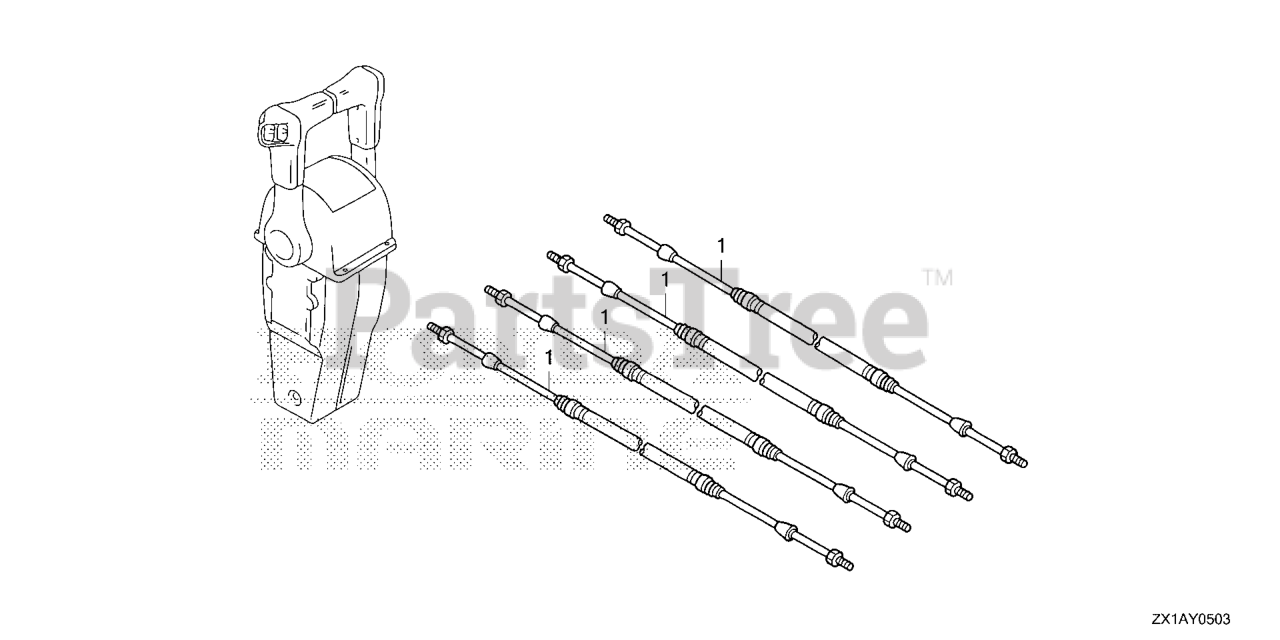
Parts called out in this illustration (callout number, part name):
1	CABLE ASSY., PUSH-PULL (33HPC-5FT)
1	CABLE ASSY., PUSH-PULL (33HPC-6FT)
1	CABLE ASSY., PUSH-PULL (33HPC-7FT)
1	CABLE ASSY., PUSH-PULL (33HPC-8FT)
1	CABLE ASSY., PUSH-PULL (33HPC-9FT)
1	CABLE ASSY., PUSH-PULL (33HPC-10FT)
1	CABLE ASSY., PUSH-PULL (33HPC-11FT)
1	CABLE ASSY., PUSH-PULL (33HPC-12FT)
1	CABLE ASSY., PUSH-PULL (33HPC-13FT)
1	CABLE ASSY., PUSH-PULL (33HPC-14FT)
1	CABLE ASSY., PUSH-PULL (33HPC-15FT)
1	CABLE ASSY., PUSH-PULL (33HPC-16FT)
1	CABLE ASSY., PUSH-PULL (33HPC-17FT)
1	CABLE ASSY., PUSH-PULL (33HPC-18FT)
1	CABLE ASSY., PUSH-PULL (33HPC-19FT)
1	CABLE ASSY., PUSH-PULL (33HPC-20FT)
1	CABLE ASSY., PUSH-PULL (33HPC-21FT)
1	CABLE ASSY., PUSH-PULL (33HPC-22FT)
1	CABLE ASSY., PUSH-PULL (33HPC-23FT)
1	CABLE ASSY., PUSH-PULL (33HPC-24FT)
1	CABLE ASSY., PUSH-PULL (33HPC-25FT)
1	CABLE ASSY., PUSH-PULL (33HPC-26FT)
1	CABLE ASSY., PUSH-PULL (33HPC-27FT)
1	CABLE ASSY., PUSH-PULL (33HPC-28FT)
1	CABLE ASSY., PUSH-PULL (33HPC-29FT)
1	CABLE ASSY., PUSH-PULL (33HPC-30FT)
1	CABLE ASSY., PUSH-PULL (33HPC-31FT)
1	CABLE ASSY., PUSH-PULL (33HPC-32FT)
1	CABLE ASSY., PUSH-PULL (33HPC-33FT)
1	CABLE ASSY., PUSH-PULL (33HPC-34FT)
1	CABLE ASSY., PUSH-PULL (33HPC-35FT)
1	CABLE ASSY., PUSH-PULL (33HPC-36FT)
1	CABLE ASSY., PUSH-PULL (33HPC-37FT)
1	CABLE ASSY., PUSH-PULL (33HPC-38FT)
1	CABLE ASSY., PUSH-PULL (33HPC-39FT)
1	CABLE ASSY., PUSH-PULL (33HPC-40FT)
